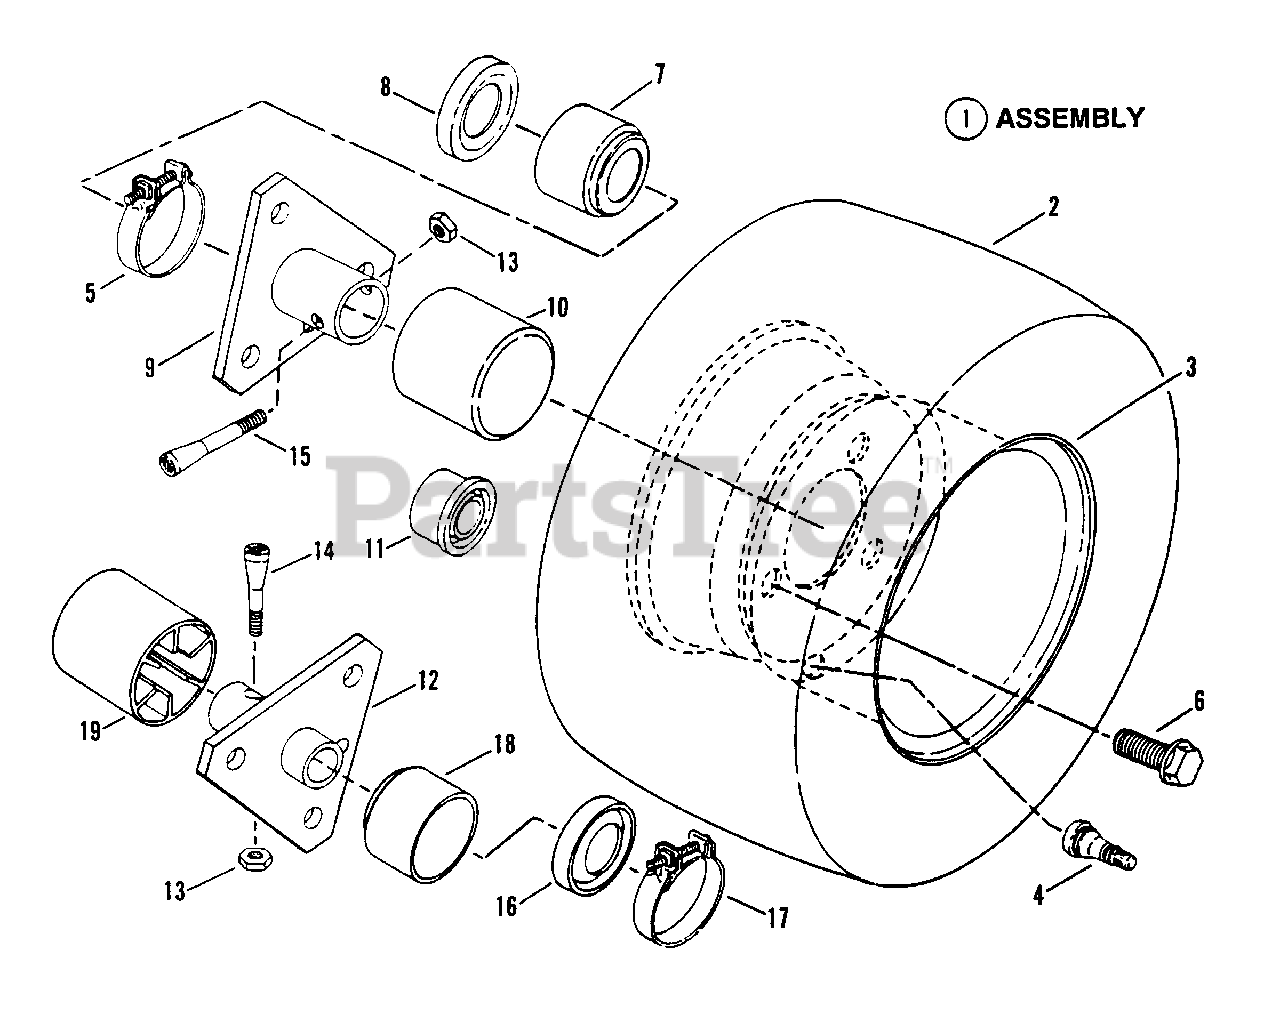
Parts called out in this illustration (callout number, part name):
1	ASSEMBLY, Rear Tire & Rim
2	TIRE, Std., 16-4.80 x 8
3	RIM, Std.
4	VALVE, Air (Snap-in)
5	CLAMP, Right Hand
6	BOLT, 1/2-20 x 3/4" Lug
7	BOOT, Right Hand
8	SEAL, Oil
9	HUB, Rear Wheel (Right Hand)
10	CAP, Hub
11	CAP, Seal L.H. 3/4"
12	HUB, Rear Wheel
13	NUT, 5/16-24 Hex Center Lock
14	BOLT, 5/16-24 x 1 5/8" Tapered (Left Hand)
15	BOLT, 5/16-24 x 2" Tapered (Right Hand)
16	SEAL, Oil (Left Hand)
17	CLAMP, (Left Hand)
18	BOOT, (Left Hand)
19	CAP, Hub (Left Hand)
